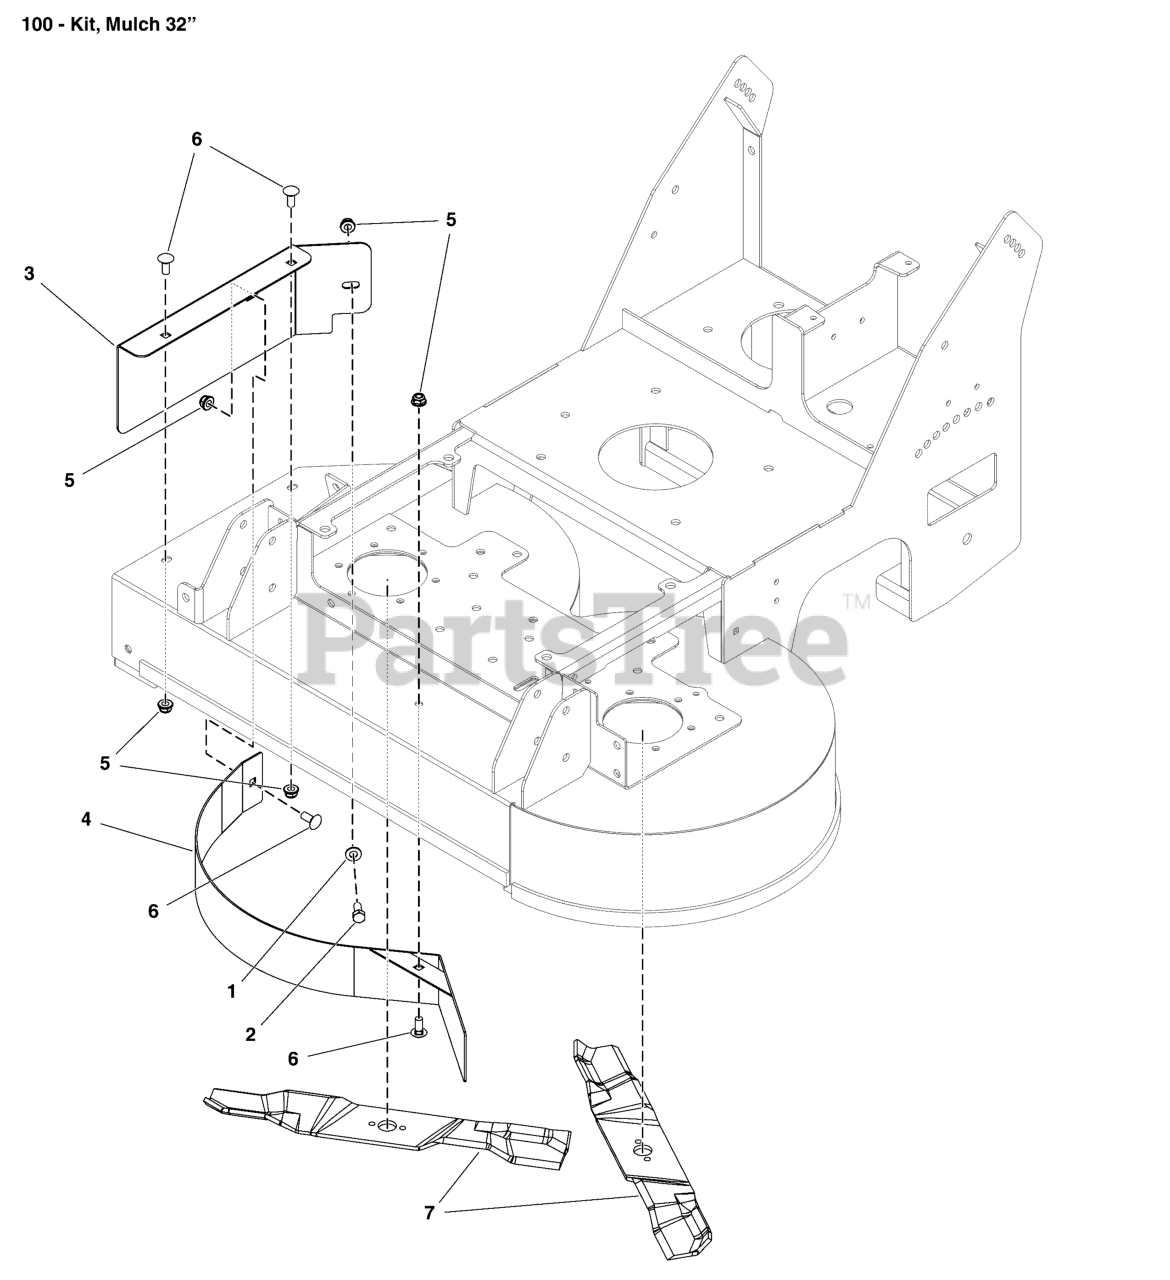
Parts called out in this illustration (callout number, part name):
1	WASHER, 5/16" SAE
2	BOLT, 5/16-18 X 3/4 GD5
3	PLATE, BLOCKOFF, 32"
4	WELD, MULCH BAFFLE, 32 - BLK
5	NUT, 5/16-18 HEX NYLOCK FLANGE NUT
6	BOLT, 5/16-18 X 3/4, CARRIAGE, GD5, CZ
7	BLADE SET, MULCH, 2 BLADES
100	KIT, MULCH, FW15 32"
